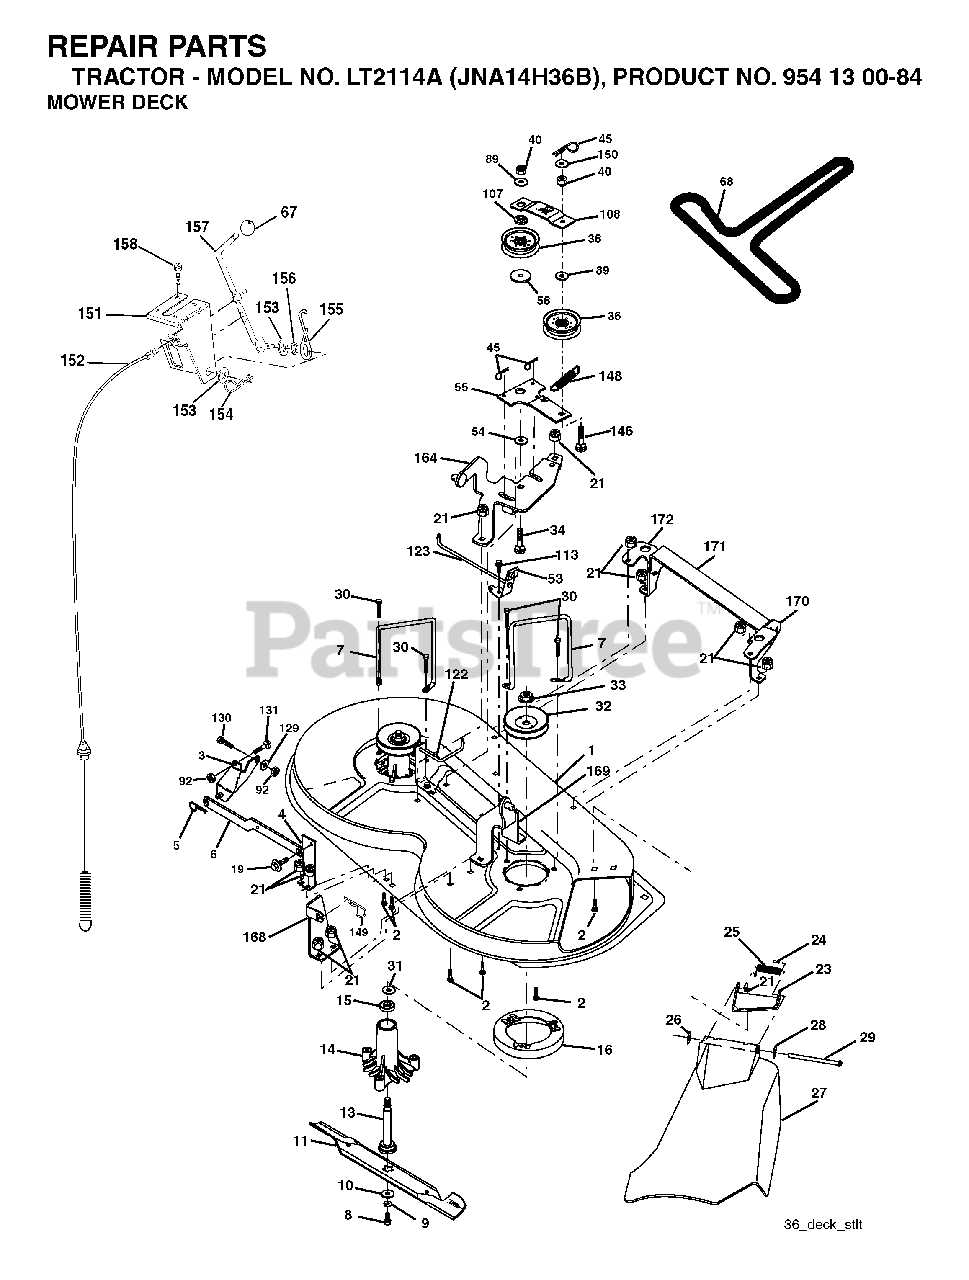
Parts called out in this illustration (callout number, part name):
2	BOLT
3	BRKT ASM SWAY BAR
5	RETAINER-SPRNG RB
6	BAR SWAY DECK
7	KEEPER LH
8	BLADE BOLT
9	LOCKWASHER
10	WASHER.BLADE
11	BLADE.36".MULCH
13	SHAFT ASM VENT
14	HSG MANDREL
16	STRIPPER, MWR ROUND
19	BOLT SHD 5/16-18
21	LOCKNUT
23	BRACKET ASM DEFLECTOR
24	CAP-SLEEVE LT
25	SPRING TORSION
26	NUT PUSH M
28	WASHER
29	HINGE ROD
30	SCREW, WASHER HEAD
31	WASHER
32	PULLEY, MANDREL
33	NUT, FLG TOPLOCK 9/16"
34	BOLT
36	FLAT IDLER PULLEY
40	LOCKNUT
45	RETAINER M
53	BRAKE ASSEMBLY
55	IDLER ARM
56	SPACER.RETAINER.MOWER
67	KNOB T (3/8 HOLE)
68	V-BELT.MOWER.
89	WASHER GT
92	NUT
107	SPACER.IDLER.ARM
108	STIFFENER.IDLER.ARM
129	WASHER
131	BOLT D
146	BOLT, CARRIAGE IDLER
148	IDLER RETURN SPRING
149	SPRING.RETAINER.YELLOW.ZINC
150	WASHER PM
151	BRACKET, CLUTCH CABLE
153	WASHER FLAT 3/8"
154	SPRING RETAINER
155	SPRING RETENTION LEVER
156	SPACER CLUTCH CABLE
157	ROD CLUTCH CABLE 3/8"
158	SCREW
171	BRACE
